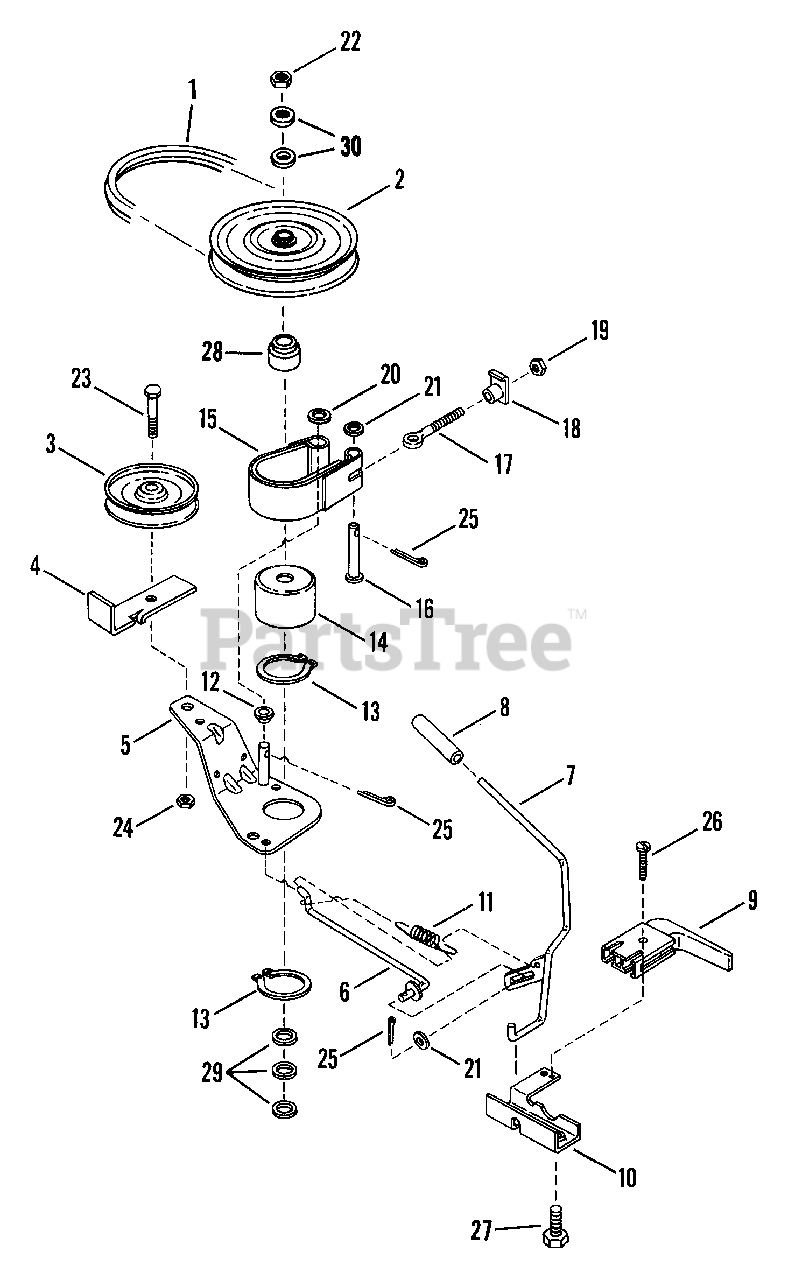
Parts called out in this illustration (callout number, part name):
1	BELT, Drive 28 & 30" Models
2	PULLEY, Spindle
3	PULLEY, Idler
4	RESTRICTOR, Belt
5	ARM, Idler
6	ROD, Idler
7	HANDLE, Blade ON-OFF (Lever)
8	GRIP, Handle
9	SWITCH, Deck Interlock
10	MOUNT, Handle
11	SPRING, Blade Handle
12	SPACER
13	RING, 2" External Retaining
14	DRUM, Brake
15	BAND, Brake
16	PIN, 1/4x1-5/8" Clevis
17	BOLT, 1/4-20 Eye
18	NUT, 1/4-20 Tee
19	NUT, 1/4-20 Hex
20	WASHER, 3/8" Flat
21	WASHER, 1/4 Flat
22	NUT, 3/4-16 Hex Jam
23	SCREW, 3/8-24x1 3/4" Hex Head Cap
24	NUT, 3/8-24 Hex Lock
25	PIN, 3/32x3/4" Cotter
26	SCREW, #10-32x1" Self-Tapping
27	SCREW, 1/4-20x5/8" Self-Tapping
28	HUB, Pulley
29	WASHER, 49/64x1-1/8" Flat
30	WASHER, 49/64x1-1/2" Flat
